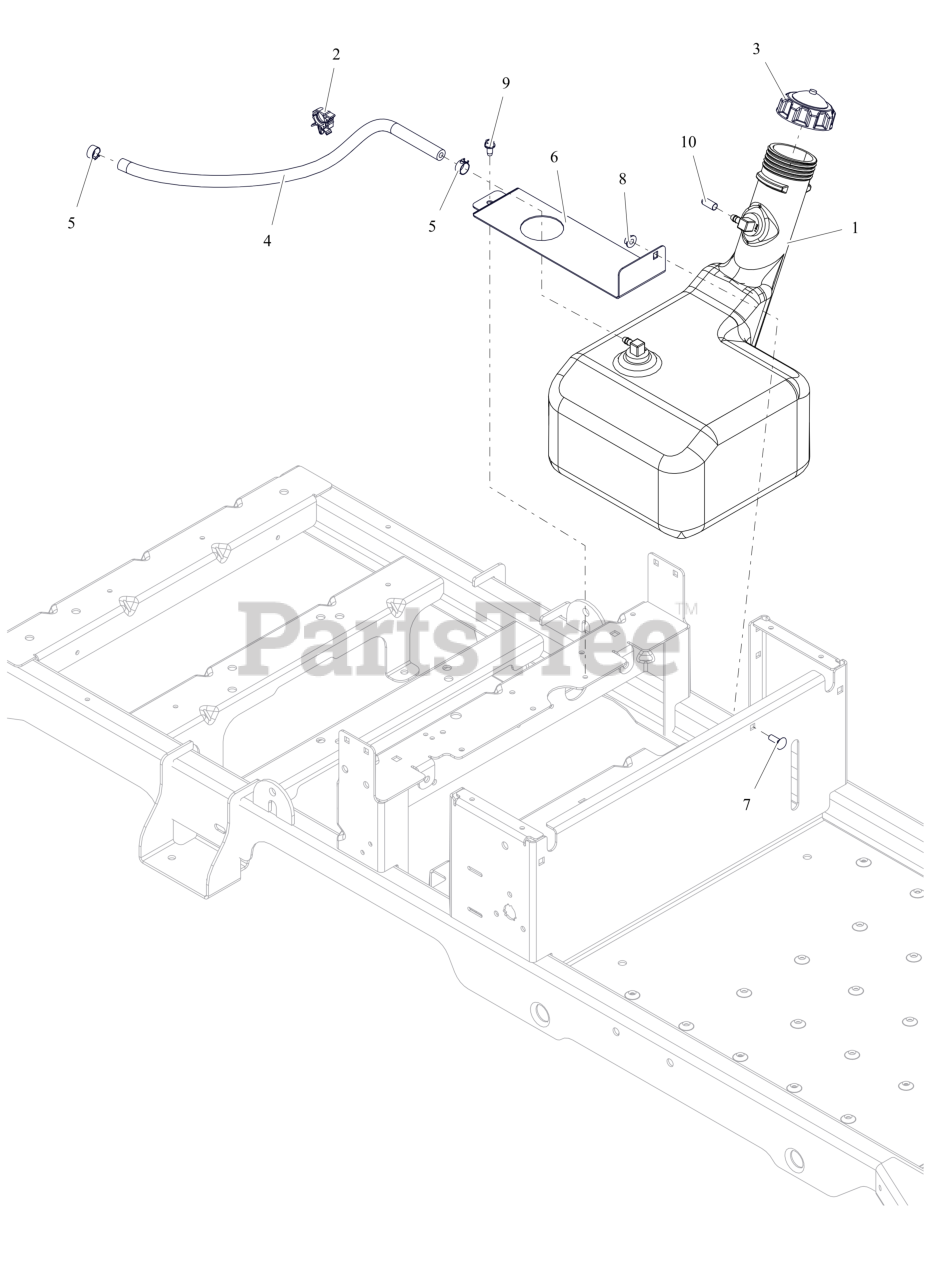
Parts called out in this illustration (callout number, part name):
1	ASM, FUEL TANK-ZOOM
2	WIRE CLIP
3	FUEL CAP
4	HOSE, .25 LOW-PERM BULK GAS
5	CLAMP, FUEL LINE
6	BRKT, TANK STRAP
7	BLT, RHSN .25-20X.750 G5 ZCC
8	NUT-LK-CTR-FLG .25-20 ZC120
9	SCR-TAP .25-20X.50 HWH ZCC
10	VINYL CAP, 7.5X19MM BLACK
